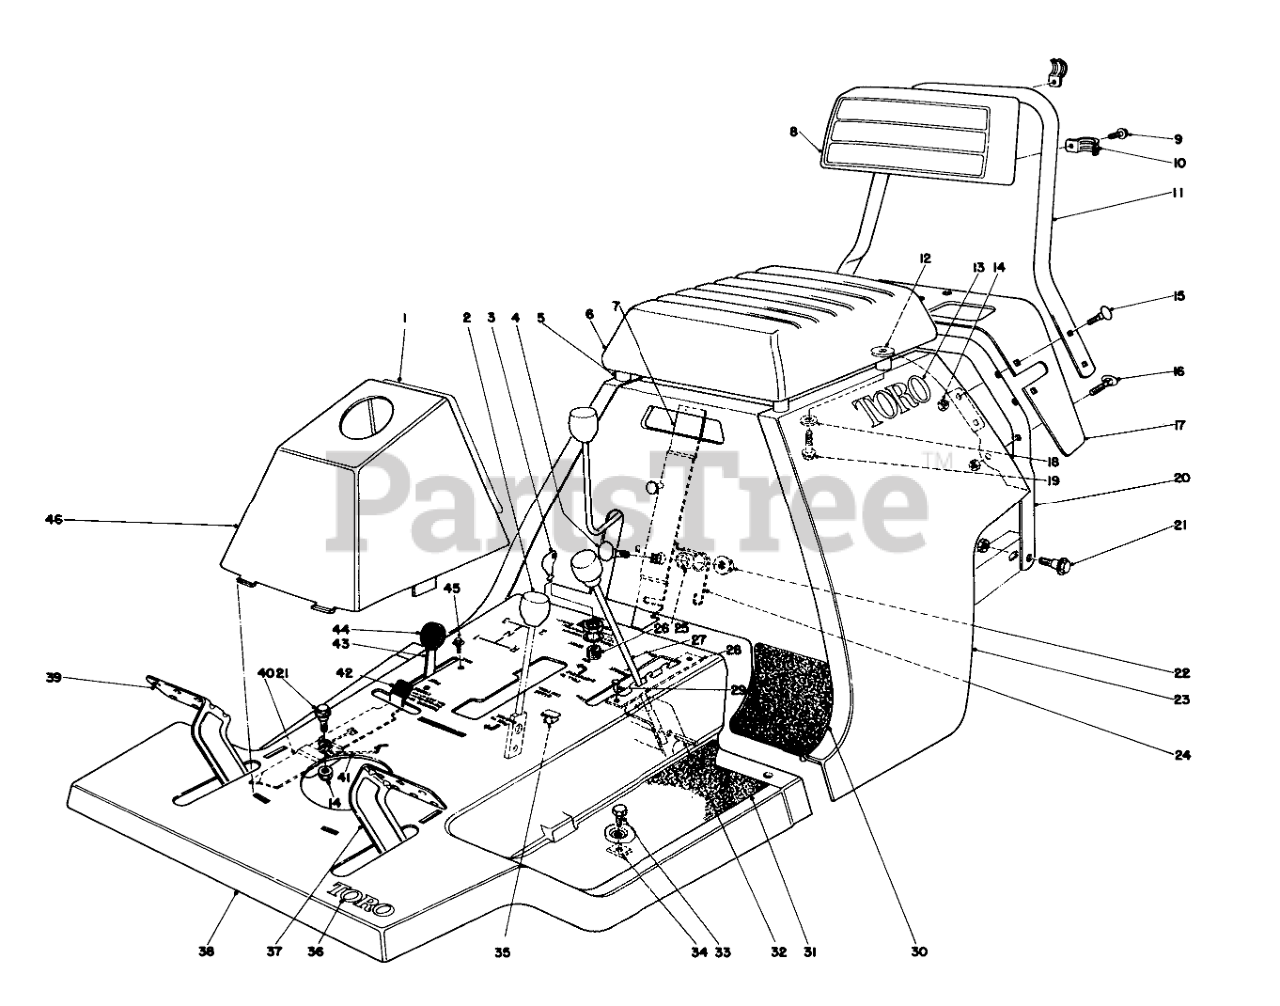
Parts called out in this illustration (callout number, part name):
1	Decal Tower
3	Key
4	BOLT-CARR
5	Spacer
7	Handle Latch
8	Backrest
9	SCREW-HHF
10	CLAMP-CONDUIT
11	Handle Upper
12	WASHER-FLAT
13	Decal
14	NUT-LOCK, CONE
15	SCREW-CARR
16	HANDLE SCREW
17	Extension Rear Body
18	WASHER-FLAT
19	HEX FLANGE SCREW
20	Handle Lower
21	SCREW-SHOULDER
22	NUT-HF
23	Rear Body
24	Latch Return Spring
25	Spacer
26	STARTER SWITCH
27	Height of Cut Lever
28	Height Adjustment Plate
30	Heel Pad-LH.
31	Foot Tread LH.
32	PIN-SPECIAL
33	SCREW-HH
34	NUT-TINNERMAN
35	Wire & Cable Tie
36	DECAL
37	Clutch Pedal
38	Body-Front (Incl. Ref. #28 & 29)
39	Brake Pedal
40	Parking Brake
41	SPRING-PARKING BRAKE
42	TIP-PARKING BRAKE
43	Throttle Control (Incl. Ref. #44)
45	8X1/2 SELF TAP SCREW
46	Tower
